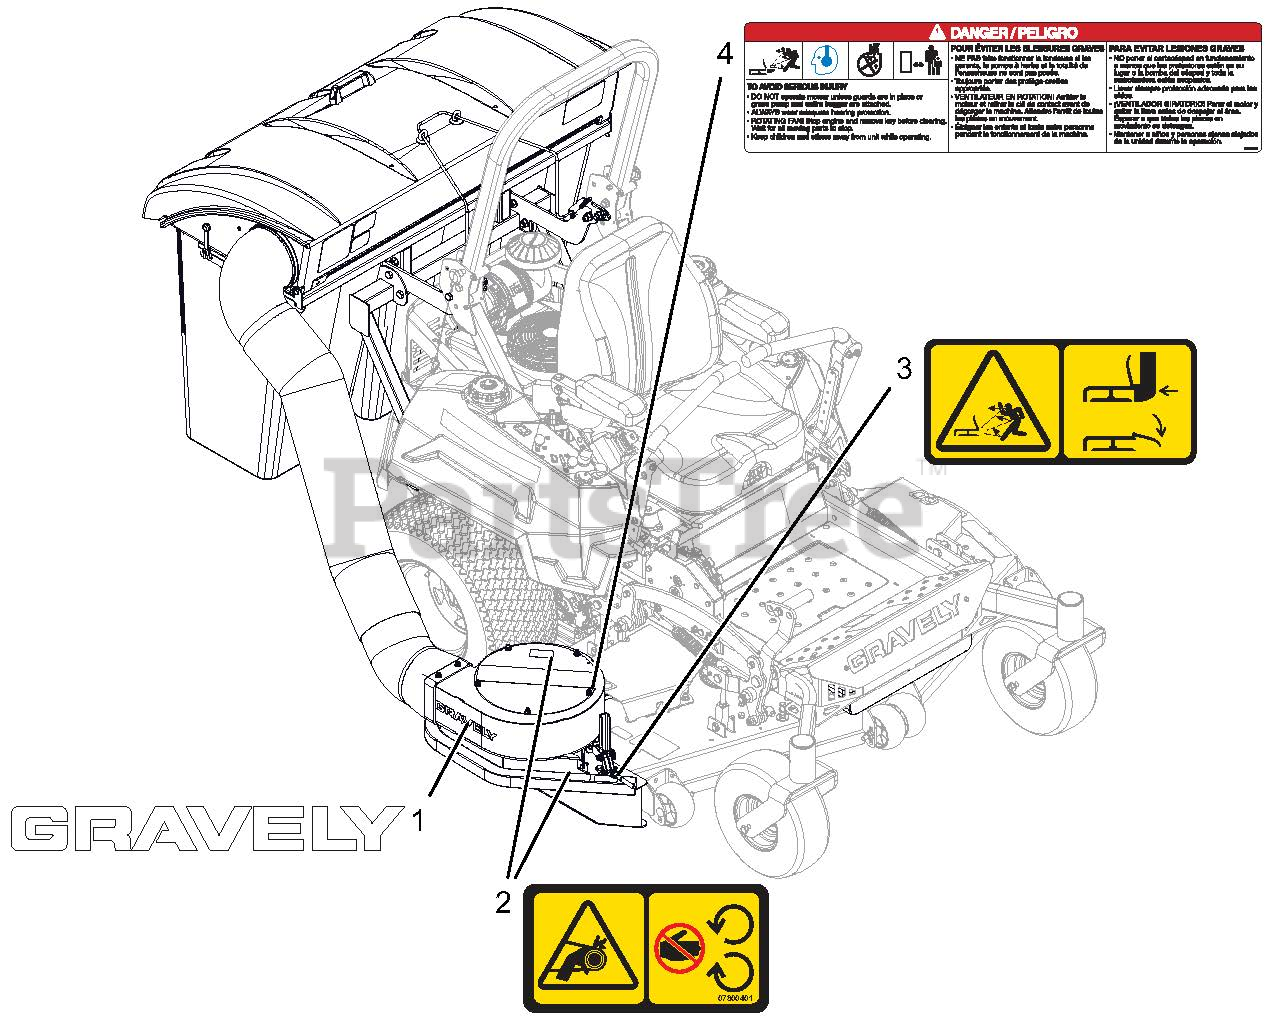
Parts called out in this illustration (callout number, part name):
1	DECAL, 9.5" GRAVELY LOGO
2	DECAL, SAFETY - GUARDING
3	DECAL, SAFETY - DECK GUARDING
4	DECAL, CAUTION GRASS PUMP
